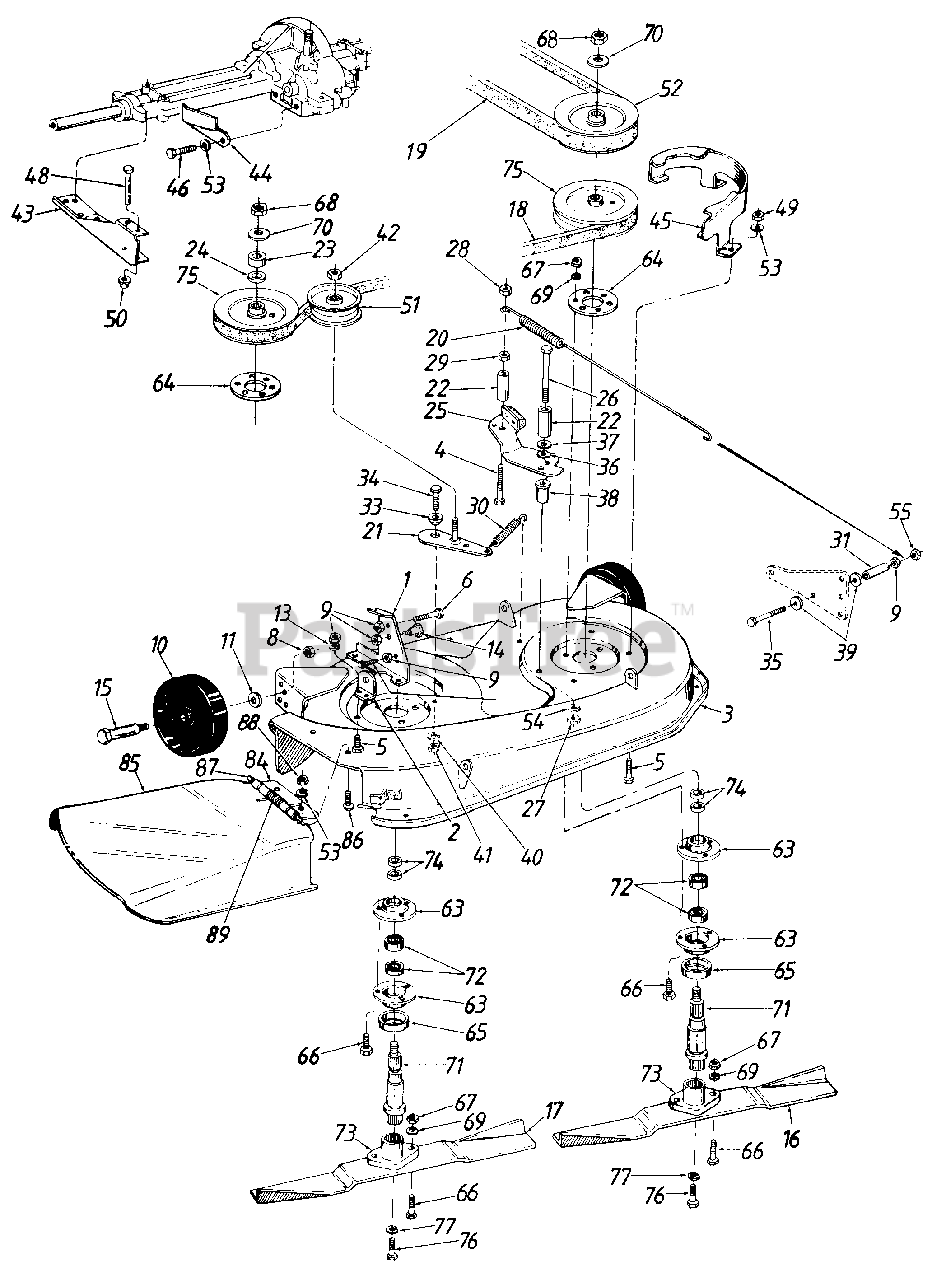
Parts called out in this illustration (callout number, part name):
1	Deck Disengagement Brkt.
2	Rear Deck Brkt. R.H.
3	32" Deck Ass'y.
4	Hex Bolt 1/4-28 x 1.75" Lg.
5	Hex Bolt 1/4-20 x .62" Lg.
6	Hex Wash. Hd. Scr. 1/4-20 x 1.5" Lg.
8	Hex L-Nut 3/8-16 Thd.
9	Hex Nut 1/4-20 Thd.
10	Deck Wheel
11	Bell-Wash. .380" I.D. x .88
13	L-Wash. 1/4" I.D.
14	Shld. Bolt .500" Dia. x .215"
15	Shld. Bolt .498" Dia. x 1.53"
16	L.H. High-Lift Blade
17	R.H. High-Lift Blade
18	V-Belt
19	V-Belt
20	Extension Spring 15-5/8" Lg.
21	Idler Brkt. Ass'y.
22	Spacer 5/16" I.D. x 1/2" O.D. x 31/32"
23	Spacer 3/4" I.D. x 1-1/4" O.D. X 1/2 "
24	Spacer 3/4" I.D. x 1-1/4" O.D. x 3/16"
25	Deck Brake Brkt. Ass'y.
26	Hex Bolt 5/16-18 x 3.25" Lg.
27	Hex Nut 5/16-24 Thd.
28	Hex L-Nut 1/4-28 Thd.
29	Hex Nut 1/4-28 Thd.
30	Extension Spring 4.35" Lg.
31	Spacer 1/4" I.D. x 3/8" O.D. x 1-5/16"
33	Shoulder Spacer
34	Hex Bolt 3/8-16 x 1" Lg.
35	Hex Bolt 1/4-20 x 2.5" Lg.
36	Wave Washer
37	Shld. Spacer .27" Lg.
38	Spacer 1.46" Lg.
39	Flat Wash. 1/4"
40	L-Wash. 3/8" I.D.
41	Hex Nut 3/8-16 Thd.
42	Hex L-Nut 3/8-24 Thd.
43	Lower Outside Belt Guard
44	Lower Inside Belt Guard
45	Belt Guard Deck R.H.
46	Hex Bolt 1/4-20 X .62" Lg.
49	Hex Nut 1/4-20 Thd.
50	Speed Nut 1/4" Rod
51	Flat Idler Pulley
52	5" Dia. Pulley
53	L-Wash. 1/4" I.D.
54	Bell-Wash. 5/16" I.D.
55	Hex L-Nut 1/4-20 Thd.
63	Bearing Housing
64	Reinforcement Plate
65	Bearing Shield
66	Hex Bolt 5/16-24 x 1.0" Lg.
67	Hex Nut 5/16-24 Thd.
68	Hex Jam Nut 5/8-18 Thd.
69	L-Wash. 5/16" I.D.
70	Bell-Wash. 5/8" I.D.
71	Blade Spindle
72	Ball Bearing
73	Blade Adapter
74	Spacer
75	5" Dia. Pulley
76	Hex Bolt 3/8-24 x 1.0" Lg.
77	L-Wash. 3/8" I.D. H.D.
84	Chute Bracket
85	Chute
86	Truss.-Mach. Scr. 1/4-20 x .75" Lg.
87	Hinge Pin
88	Hex Nut 1/4-20 Thd.
89	Torsion Spring 1.14" Lg.
